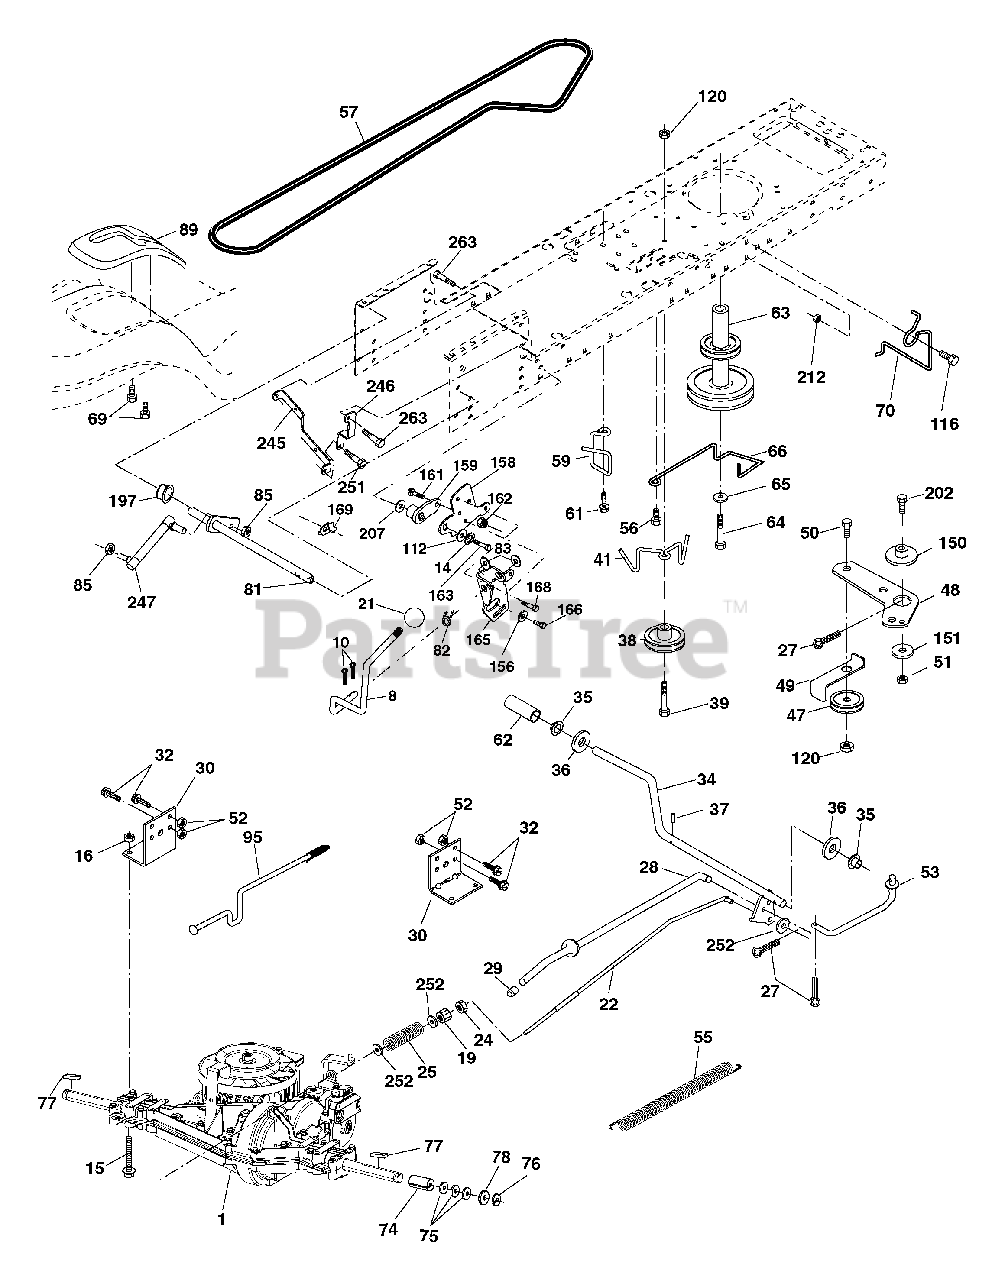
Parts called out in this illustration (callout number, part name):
8	Rod Shift
10	Pin Cotter 1/8 x 1 CAD
14	Washer Lock Hvy Helical
15	Bolt, Hex FLGHD 5/16-18 Gr. 5
16	Nut Lock Hex W/Ins 5/16-18 unc
19	Nut Lock Hex W/Wsh 3/8-16 unc
21	Knob, Round 1/2-13
22	Rod, Brake Hydro
24	Nut
25	Spring, Brake Rod
27	Pin Cotter 1/8 x 3/4 CAD.
28	Rod, Parking Brake
29	Cap, Parking Brake
30	Bracket, Transaxle
32	Bolt Hex Hd 5/16-18 unc x 3/4
34	Shaft, Foot Pedal
35	Bearing, Nylon
36	Washer
37	Pin, Roll
38	Pulley, Composite
39	Bolt Rdhd 3/8-16 unc x 2-3/4 Gr. 5
41	Keeper, Belt Idler
47	Pulley, Idler, V-Groove
48	Bellcrank Clutch Grnd Drv STL
49	Retainer, Belt
50	Bolt Carr Sh 3/8-16 x 1-1/2 Gr. 5
51	Nut Crownlock 3/8-16 unc
52	Nut Crownlock 5/16-18 unc
53	Link, Clutch
55	Spring, Return, Clutch
56	Screw 3/8-16 x 1-1/4
57	V-Belt, Ground Drive
59	Keeper, Center Span
61	Screw 3/8-16 x .875
62	Cover, Pedal
63	Pulley, Engine
64	Bolt Hex 7/16-20 x 4 x Gr. 5-1.5 Thr
65	Washer
66	Keeper Belt Engine
69	Screw Hex Wsh. Hi-Lo 1/4 x 1/2 unc
70	Guide Belt
74	Spacer, Axle
75	Washer 25/32 x 1-1/4 x 16 Ga.
76	E-Ring
77	Key, Square
78	Washer 25/32 x 1-5/8 x 16 Ga.
81	Shaft Asm. Cross Hydro
82	Spring Torsion T/A
83	Washer 17/32 x 3/4 x 16 Ga.
85	Nut Lock Center 1/4-28
89	Console, Shift
95	Disconnect Asm. Rod Bypass LTH
112	Washer 9/32 x 3/4 x 10 Ga.
116	Bolt RDHD SQNK 3/8-16 unc x 1
120	Nut Lock Flg 3/8-16 unc
150	Spacer Retainer
151	Washer 13/32 x 2 x 10 Ga.
156	Washer Srrted 5/16 ID x 1.125
158	Bracket Shift Mount
159	Hub Shift
161	Bolt Rdhd Sqnk 1/4-20 x 3/4 Gr. 5
162	Nut Crownlock 1/4-20 unc
163	Bolt Hex Fin 1/4-20 unc x 1 Gr. 5
165	Bracket Pivot Lever
166	Screw 5/16-18 x 5/8
168	Bolt Shoulder 5/16-18 x .561
169	Plate Fastening Lt
197	Nyliner Snap-In 5/8" ID
202	Bolt Carr Sh 3/8-16 x 1-3/4 Gr. 5
207	Washer Nyl 7/8 ID x .105
212	Nut Hex fl ange Lock
245	Strap Torque LH
246	Strap Torque RH
247	Link Shift Transaxle
251	Screw 5/16-18 x 1
252	Washer 13/32 x 1 x 16 Ga.
263	Screw Hex Wsh Thdr 3/8-16 x 3/4
